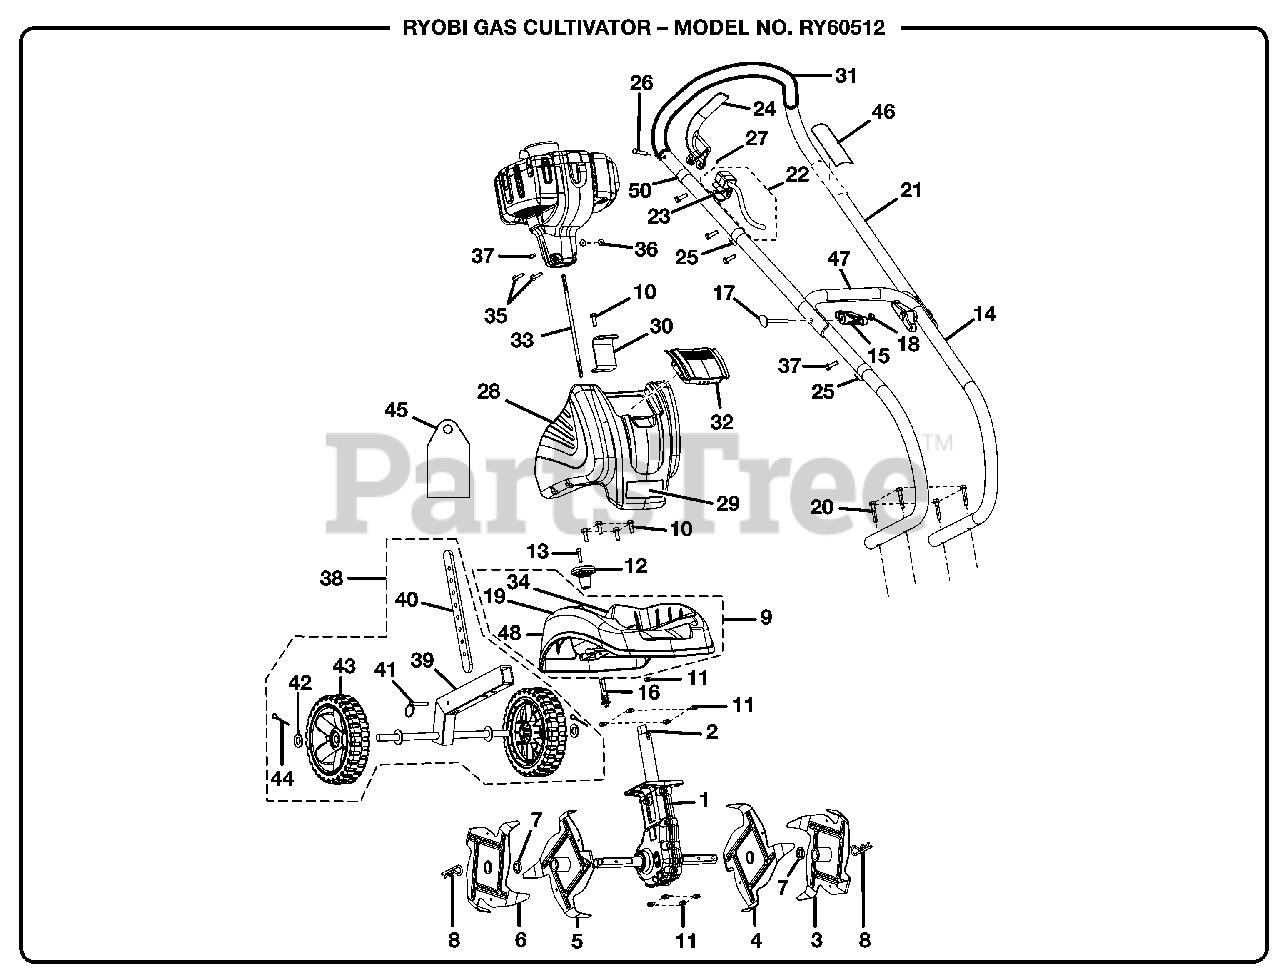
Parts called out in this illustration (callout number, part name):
1	Gear Box Assembly with Tube
2	Liner - Drive Tube
3	Tine A, Outer Right
4	Tine B, Inner Right
5	Tine C, Inner Left
6	Tine D, Outer Left
7	Felt Washer
8	Hitch Pin
9	Tine Shield Assembly
10	Bolt (1/4-20 x 1 in.)
11	Lock Nut (1/4-20)
12	Adjustment Knob
13	Screw (M5 x 16 mm Pan Hd.)
14	Lower Handle Assembly
15	Handle Bar Knob (1/4-20)
16	Receiver Retainer Assembly
17	Carriage Bolt (1/4-20 x 2-1/4 in.)
18	Acorn Nut (1/4-20)
19	Warning Label, Foot
20	Handle Bolt (1/4-20 x 1.53 in.)
21	Upper Handle Assembly
22	Throttle Cable Assembly
24	Throttle Lever
26	Throttle Lever Pin
27	Retaining Ring
28	Just Add Sand™ Tank Assembly
29	Logo Label
30	Mounting Bracket
32	Just Add Sand™ Lid
33	Flexible Drive Shaft
34	Wheel Accessory Label
35	Bolt (10-24 x 1-1/4 in.)
36	Lock Nut (10-24)
37	Screw (8-16 x 1/2 in.)
38	Wheel/Drag Bar Assembly
39	Wheel Frame
41	Quick Release Pin
42	Flat Washer
43	Wheel Assembly (6 in Dia.)
44	Cotter Pin (Split Pin)
45	Warning Hang Tag
46	Boom Warning Label
47	Starting Label
48	Warning Label
50	Rope Clip
